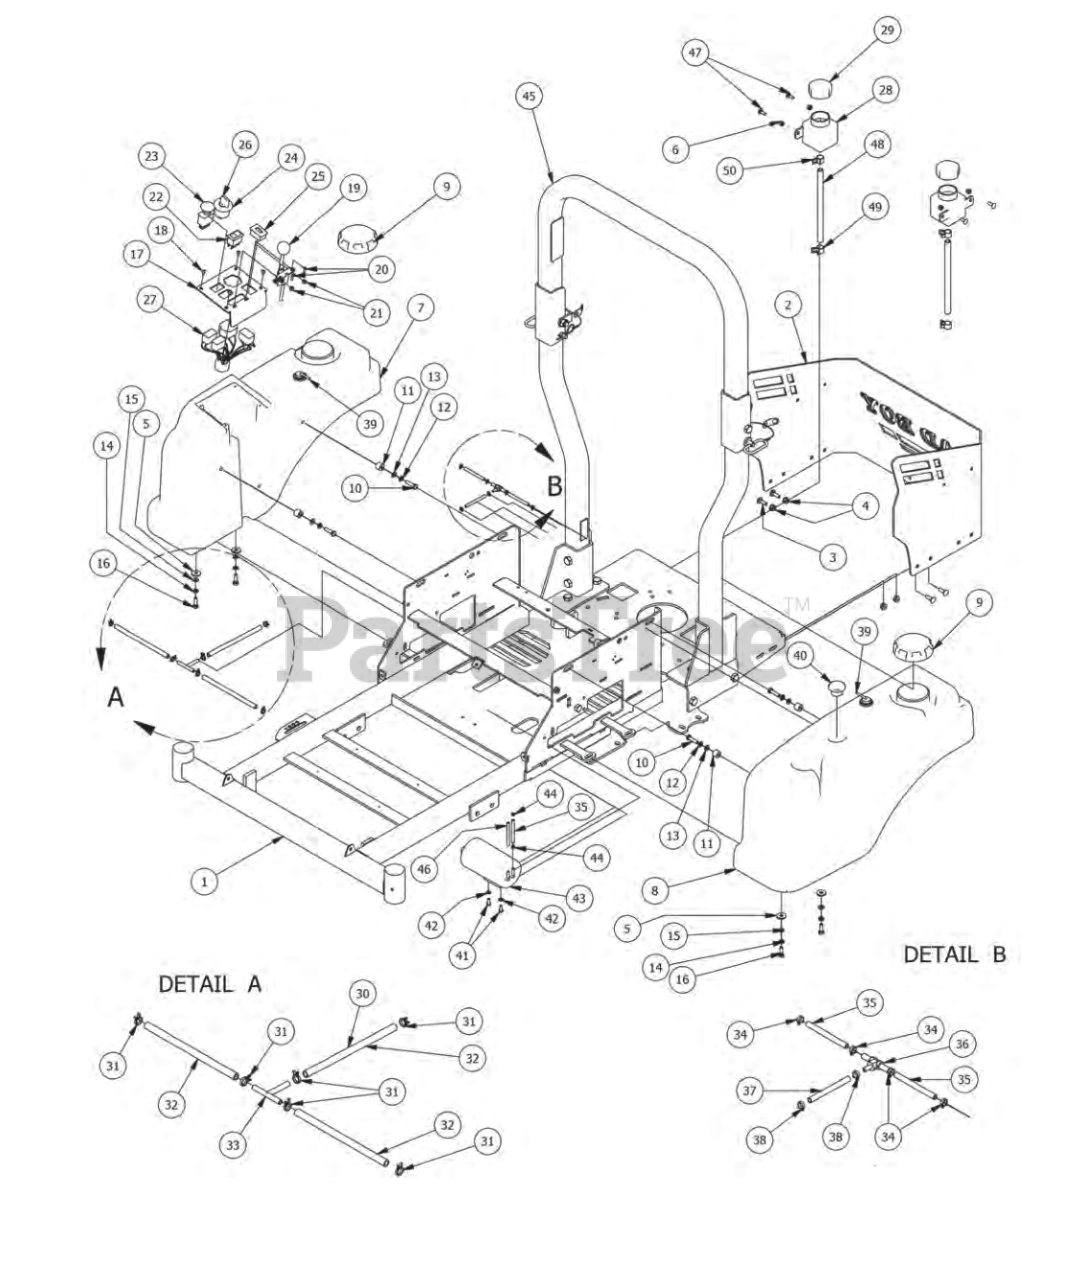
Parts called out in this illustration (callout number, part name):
1	ZT/CZT Frame 2013 Models
2	2014 ZT Rear Plate
3	5/16" x 1" Carriage Bolt
4	5/16-18 Nylon Flange Nut
5	360 ID Plastic Washer
6	1/4" Nylock Nut
7	Right Fuel Tank/Outlaw/2012/EPA
8	Left Fuel Tank/Outlaw/2012/EPA
10	5/16 x 1 1/4 Hex Bolt
11	380x.735x.470 Nylon Spacer
12	5/16" Lock Washer
13	1/4" Flat Washer
14	5/16" Lock Washer
15	1/4" Flat Washer
16	5/16" x 1" Bolt
17	2013 ZT/CZT Control Panel
18	10-32 x 3/8" Button Socket Head Bolt
19	Throttle Lever Assembly
20	10-24 X 5/8 BS C/S 18-8 SS
21	10-24 Nylon Insert Locknut
22	Rocker Deck Lift Switch - 2011
23	PTO Engager
24	Ignition Switch
25	Tachometer
26	Ignition Key
27	Harness-ZT Only-2008 and up
28	350ml Expansion Tank-CZT
29	Hydraulic Tank Cap
30	2013 ZT Fuel Line Assembly
31	1/4 fuel clamp
32	1/4" fuel line hose
33	fuel line T
34	3/16 vinyl clamp
35	3/16 vinyl tubing
36	Brass fuel line T
37	1/4" vinyl tubing
38	1/4" vinyl clamp
39	Rollover Valve-White
40	Fuel Gauge Tanks W/downtube
41	M6-1.0 X 16MM Hex Bolt
42	1/4" Lock Washer
43	Carbon Canister ZT,CZT,Outlaw
44	3/16" Vinyl Hose Clamp
45	2013 Floding ROPS CZT/ZT
46	1/4" vinyl tubing
47	1/4" x 3/4" Carriage Bolt
48	3/8 clear hose
49	1/2 Hose Clamp
50	3/8 hose clamp
